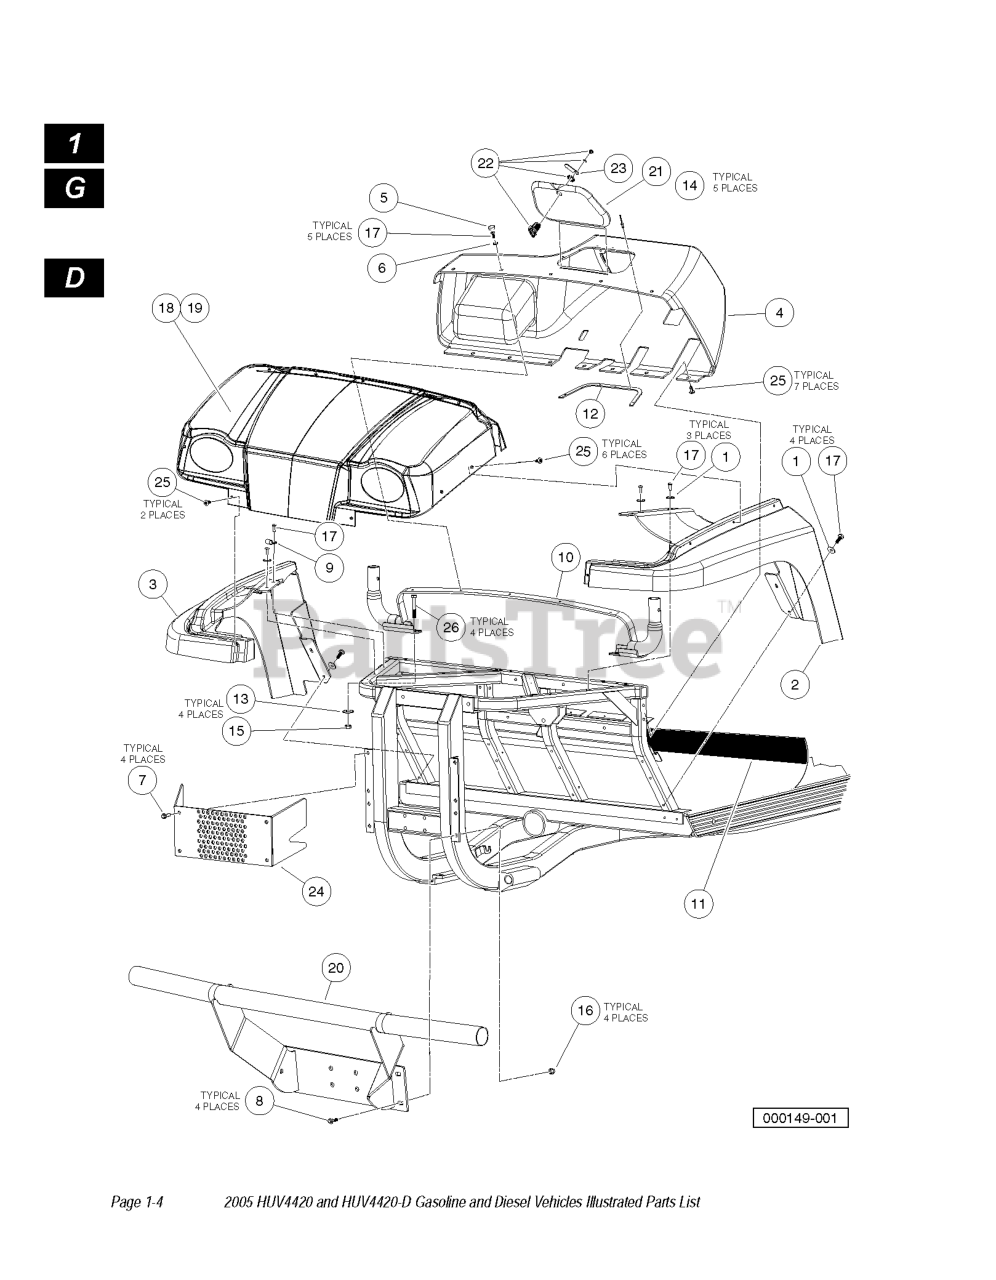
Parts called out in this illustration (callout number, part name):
2	FENDER, LEFT FRONT B
3	FENDER - RIGHT FRONT B
4	DASH BOARD WITH ACCESS HOLE
5	CAP 1/4" PLASTIC SCREW HEAD
6	WASHER 1/4 ID SCALLOPED PLAST
7	SCREW, M8 X 1.25 X 30 TRI, BLK
8	BOLT - FLANGED HD, M8 X 30.0
9	P-CLAMP, INSULATED .312 IN
10	WELDMENT, SUPP, COWL, ROPS
11	MAT, FLOOR AWD
12	SUPPORT, ACCESS PANEL, DASH
13	WASHER HARD, M10
14	RIVET, .125" DIA, .311" PANEL
15	NUT FLG M10 X 1.5 MECH DEF
16	LOCK NUT, FLG M8 X 1.25 NYLON
17	SCREW, 1/4-20X1.0 PN HD TORX
18	Cowl, Camo
19	COWL, OEM, ORANGE
20	Brush Guard
21	PANEL, ACCESS, DASH
22	CAM LOCK BODY
23	LATCH, CAM, ACCESS PANEL
24	GUARD, RADIATOR BOTTOM
25	SCREW, TUFLOK PANEL, 1/4
26	BOLT, M10 X 1.50 X 65
